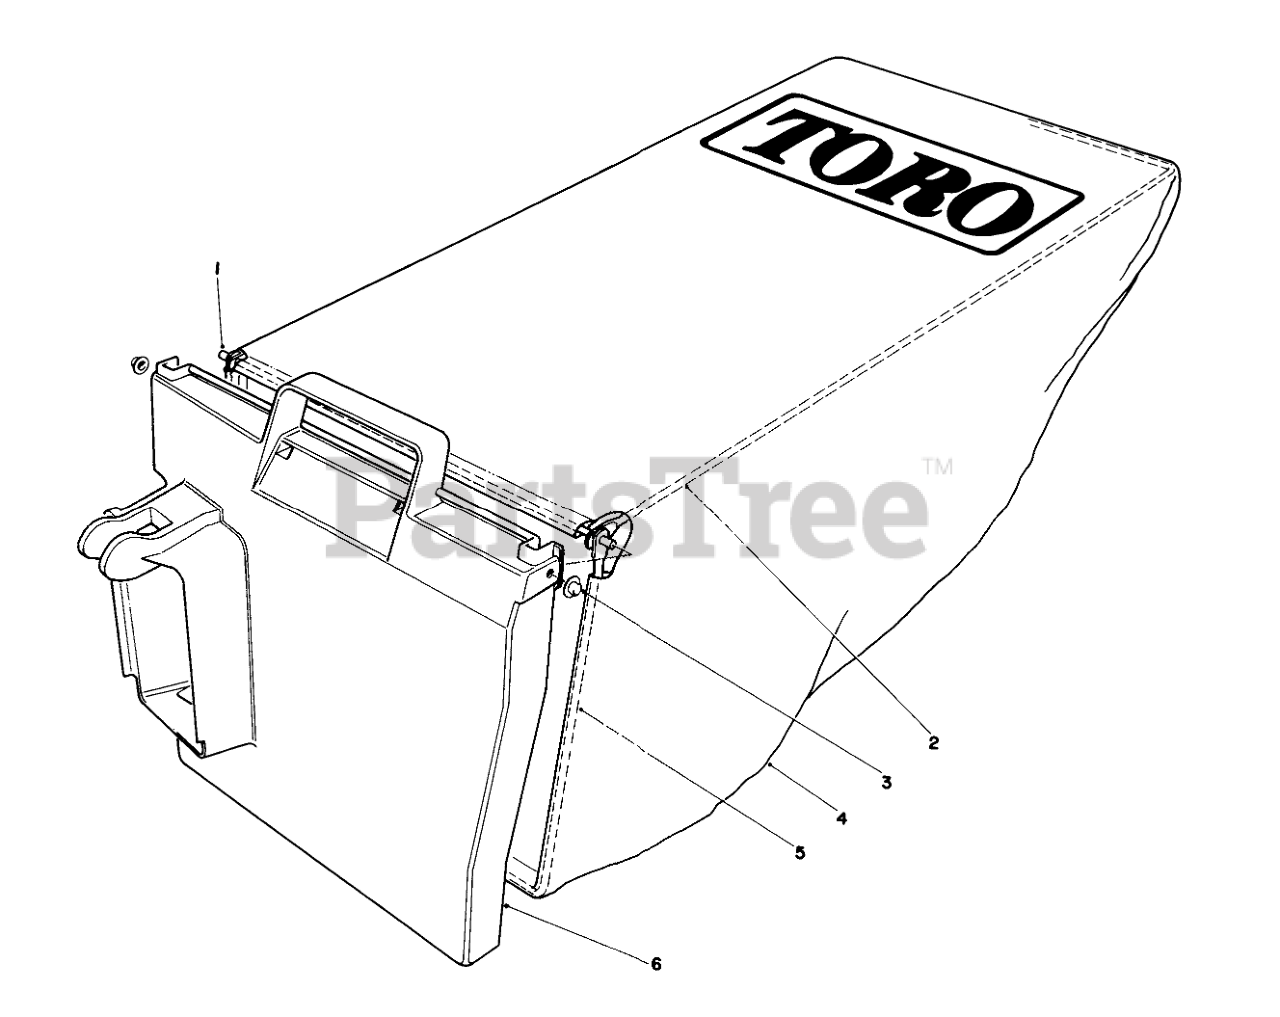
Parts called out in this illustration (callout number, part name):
1	HINGE PIN
2	BAG FRAME-UPPER
3	NUT-PUSH
4	Bag
5	Frame Bag
6	Door-Bag
